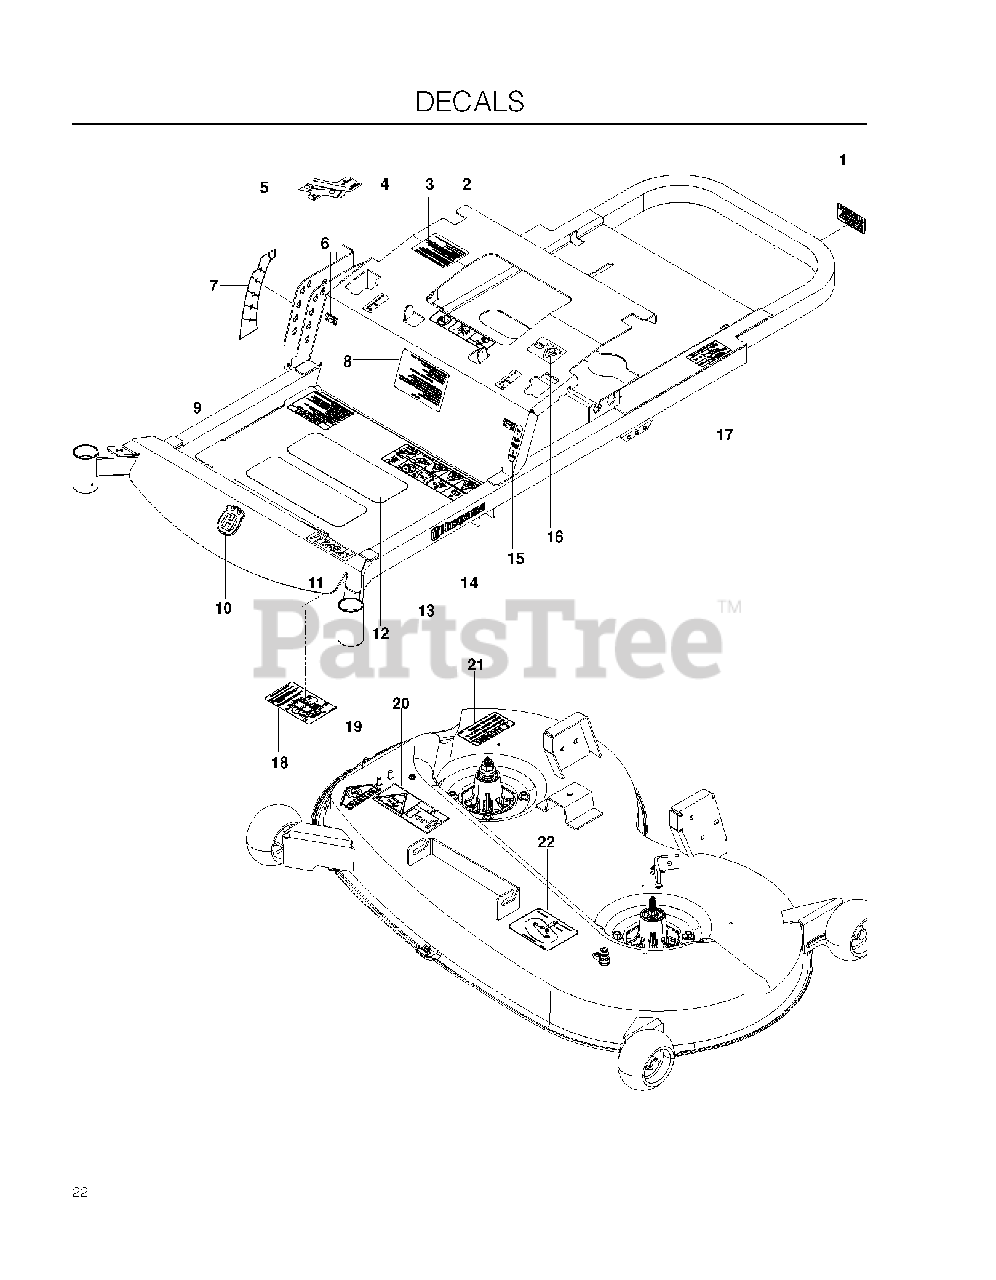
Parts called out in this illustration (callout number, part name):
1	DECAL, PROP. 65
2	EURO DECAL-BATTERY WARNIN6
3	DECAL, CUSTOMER RESPNSIBILITY
4	DECAL, MOTION CONTROL
5	DECAL, CTRL PANEL, HUSQ
6	DECAL, F.S.T.
7	DECAL, HEIGHT
8	DECAL, START
9	DECAL, WARNING
10	DECAL.AUGER.HUSQ.CROWN.SNOW
11	DECAL, RZ4623
12	ANTI-SKID PAD
13	DECAL, SAFETY WARNING
14	RP.DECAL.BADGE.170MM.TEXTLOGO
15	DECAL, PARK BRAKE
16	DECAL, EXITING MOWER
17	DECAL, DO NOT TOW
18	DECAL, SERVICE
19	DECAL, EURO SEVERING
20	DECAL, CPSC
21	DECAL, CAUTION
22	DECAL, BELT ROUTING
